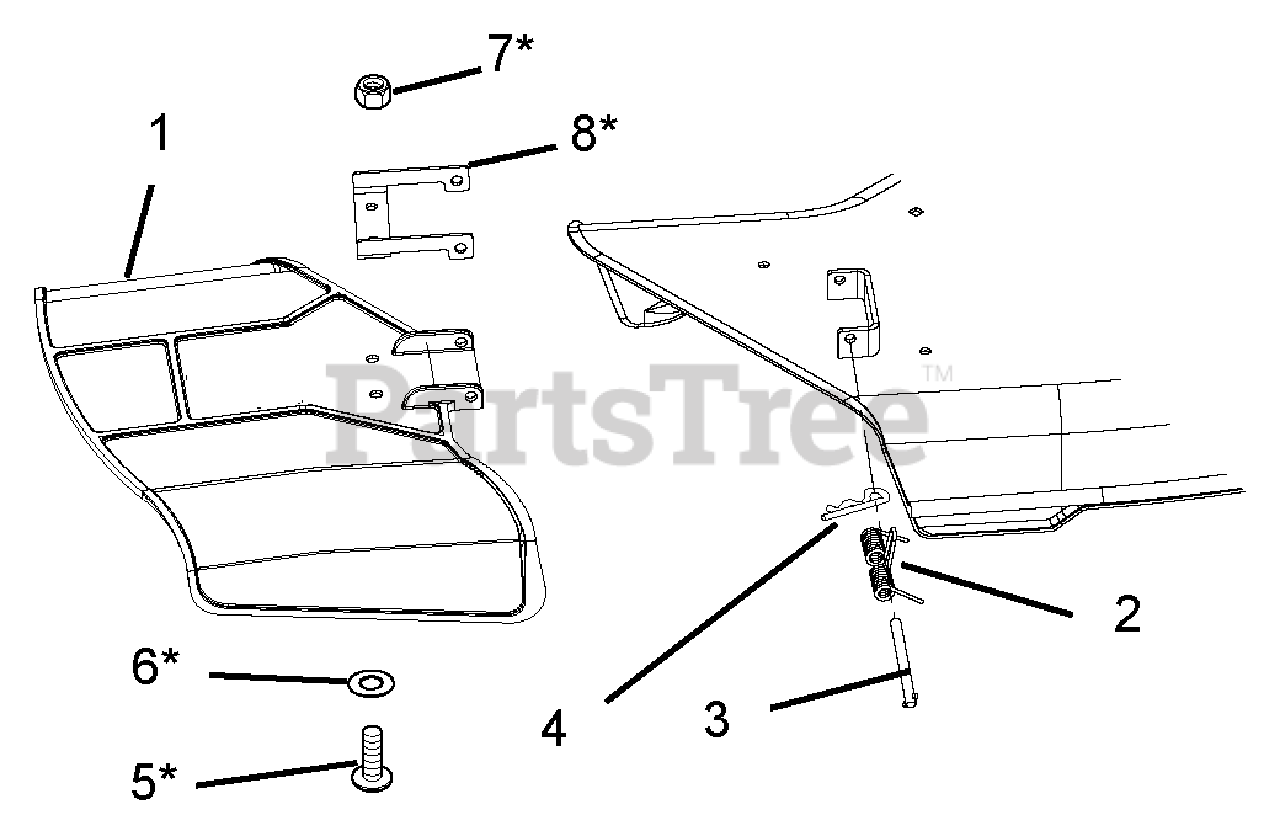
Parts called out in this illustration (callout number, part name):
1	Plastic Chute
2	Torsion Spring
3	Clevis Pin
4	Hair Pin
5	5/16 x .75 Socket Head Button Head Screw
6	7/8" Flat Washer
7	5/16" Top Lock Flange Nut
8	Chute Bracket
